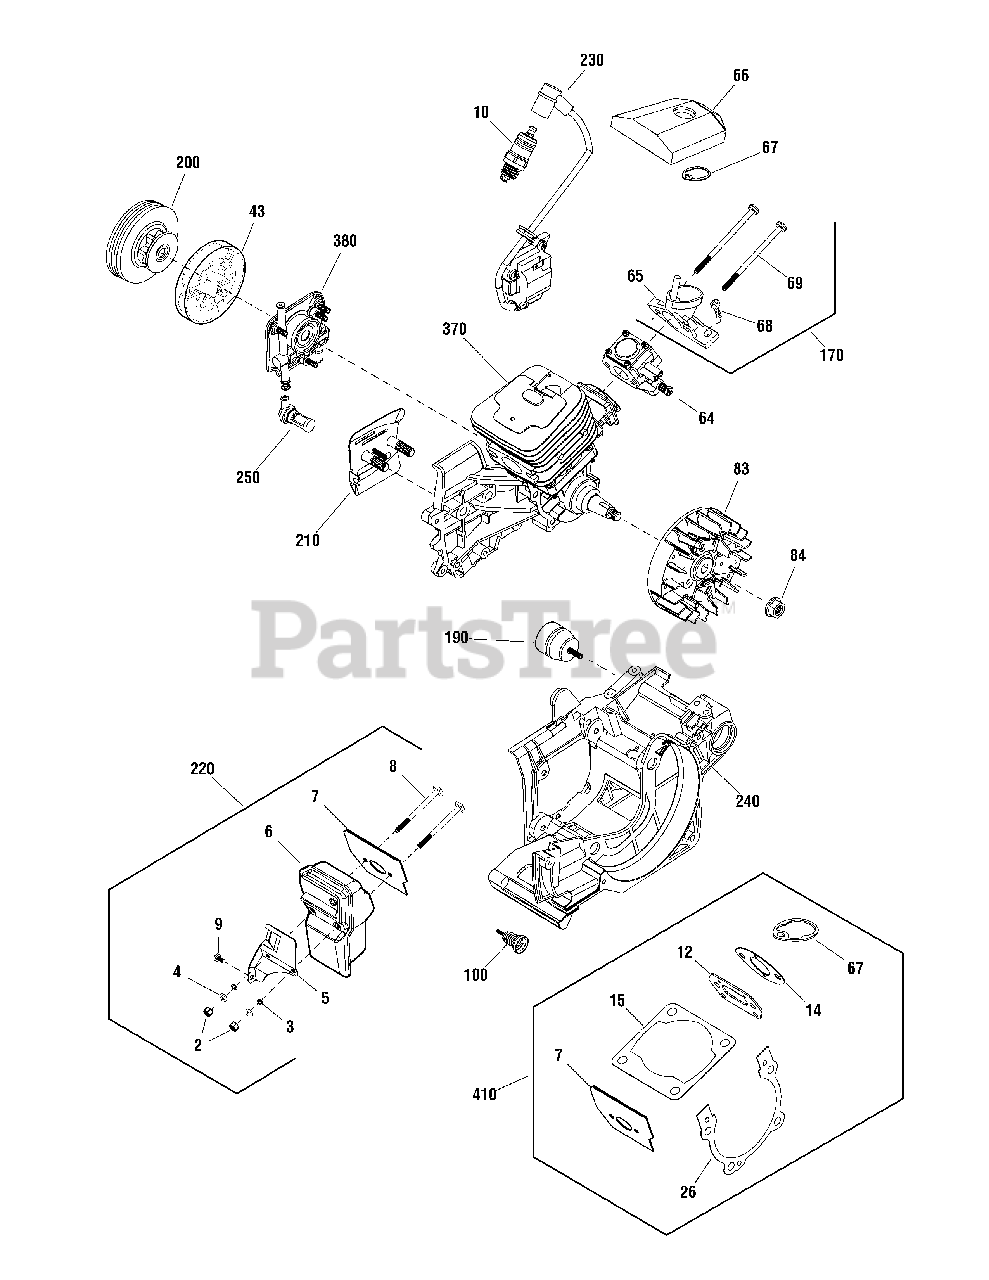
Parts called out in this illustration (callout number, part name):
2	NUT, M5
3	WASHER, Split Lock, 5
4	WASHER, 5
5	PLATE, Silencer
6	MUFFLER
7	GASKET, Muffler
8	SCREW, Muffler
9	SCREW, M5 x 12
10	SPARK PLUG, Champion
12	GASKET, Air Intake
14	GASKET, Carburetor
15	GASKET, Cylinder
26	GASKET, Crank Case
43	CLUTCH
64	CARBURETOR, Walboro WT-840A
65	SOCKET, Air Intake
66	AIR FILTER
67	GASKET, Air Filter
68	SCREW, ST4.8 x 16
69	SCREW, Carburetor
83	FLYWHEEL
84	NUT, M8
100	SPRING ASSEMBLY
170	INTAKE MANIFOLD ASSEMBLY
190	SHOCK SEAT ASSEMBLY
200	CLUTCH CUP ASSEMBLY
210	DAMPER ASSEMBLY
220	MUFFLER
230	IGNITION UNIT
240	BASE ASSEMBLY
250	FILTER, Oil
370	SHORT ENGINE, 40cc
380	OIL PUMP ASSEMBLY
410	KIT, Gaskets
